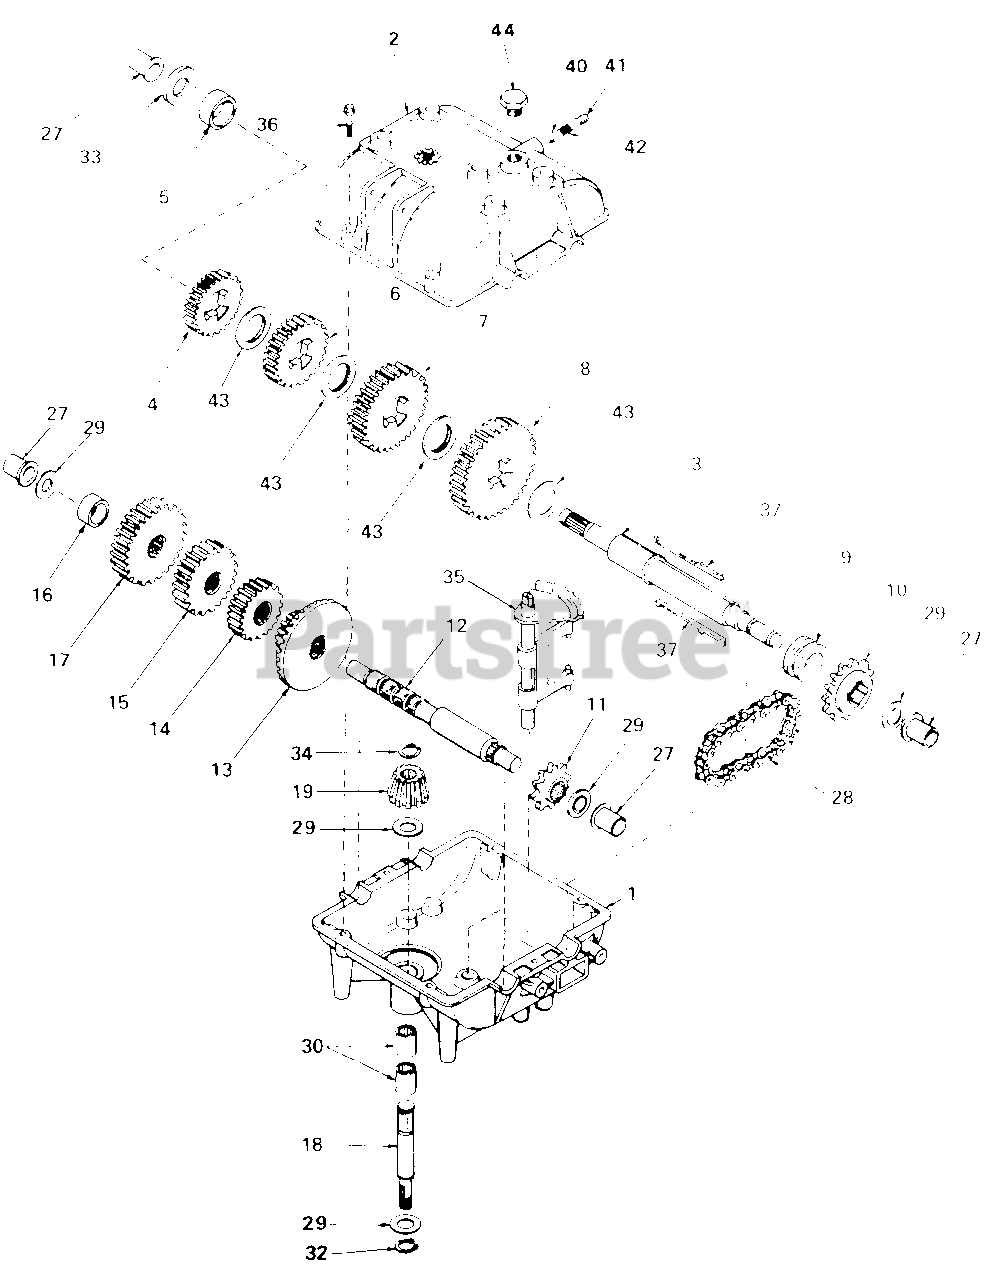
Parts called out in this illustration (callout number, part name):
1	Case, Transmission
2	Cover, Transmission
3	Shaft, Output & Brake
4	Gear, Spur (20 teeth)
6	Gear, Spur (25 teeth)
7	Gear, Spur (30 teeth)
8	Gear, Spur (35 teeth)
9	Collar, Shift
10	Sprocket (14 teeth)
11	Sprocket (10 teeth)
12	Shaft, Counter
13	Gear, Bevel (42 tooth & 15 tooth spur gear)
14	Gear, Spur (20 teeth)
15	Gear, Spur (25 teeth)
17	Gear, Spur (30 teeth)
18	Shaft, Input
19	Bevel Pinion, Input
27	Bushing, Flanged
28	Chain, Roller (No. 41 chain, 22 links)
29	Race, Thrust
30	Bearing, Needle
32	Ring, Retaining
34	Ring, Retaining
35	Rod & Fork Ass'y., Shift
36	Screw, Hex Hd. Taptite, 1/4-20 x 1 1/4
37	Key
40	Ball, Steel, 5/16"
41	Screw, Set, 3/8-16 x 3/8
42	Spring
43	Washer, Thrust
